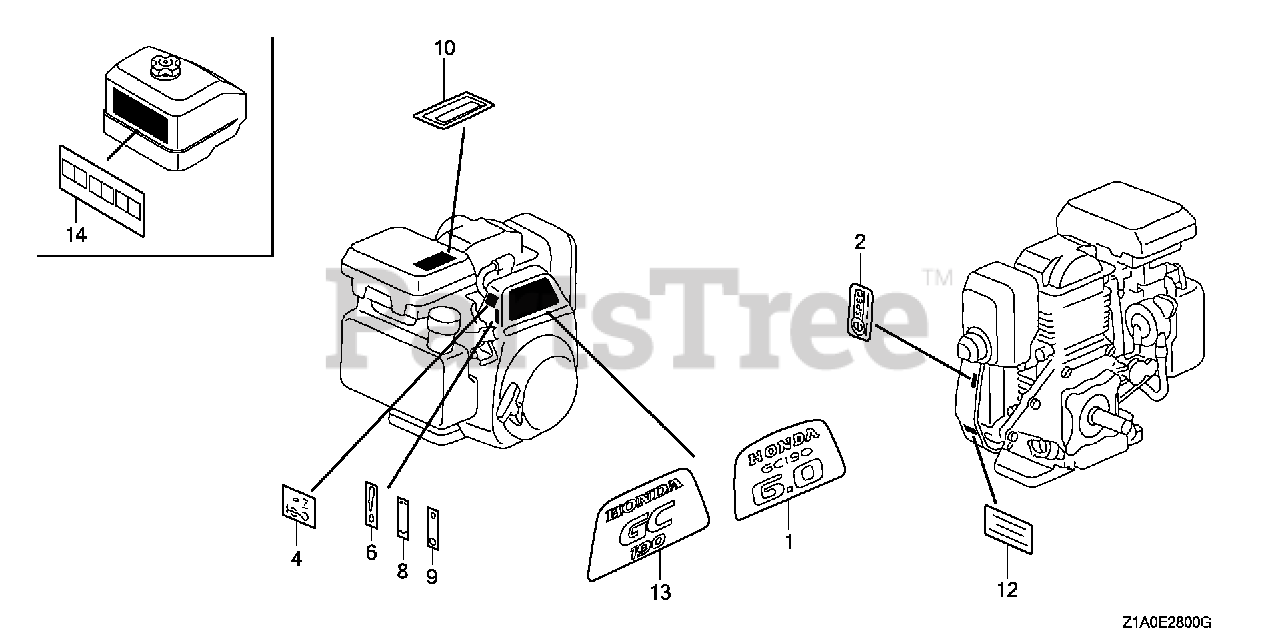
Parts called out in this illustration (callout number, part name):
1	MARK, EMBLEM (GC190)
4	MARK, CHOKE
6	MARK, THROTTLE INDICATION
12	LABEL, WARNING (NOT CERTIFIED FOR SALE)
